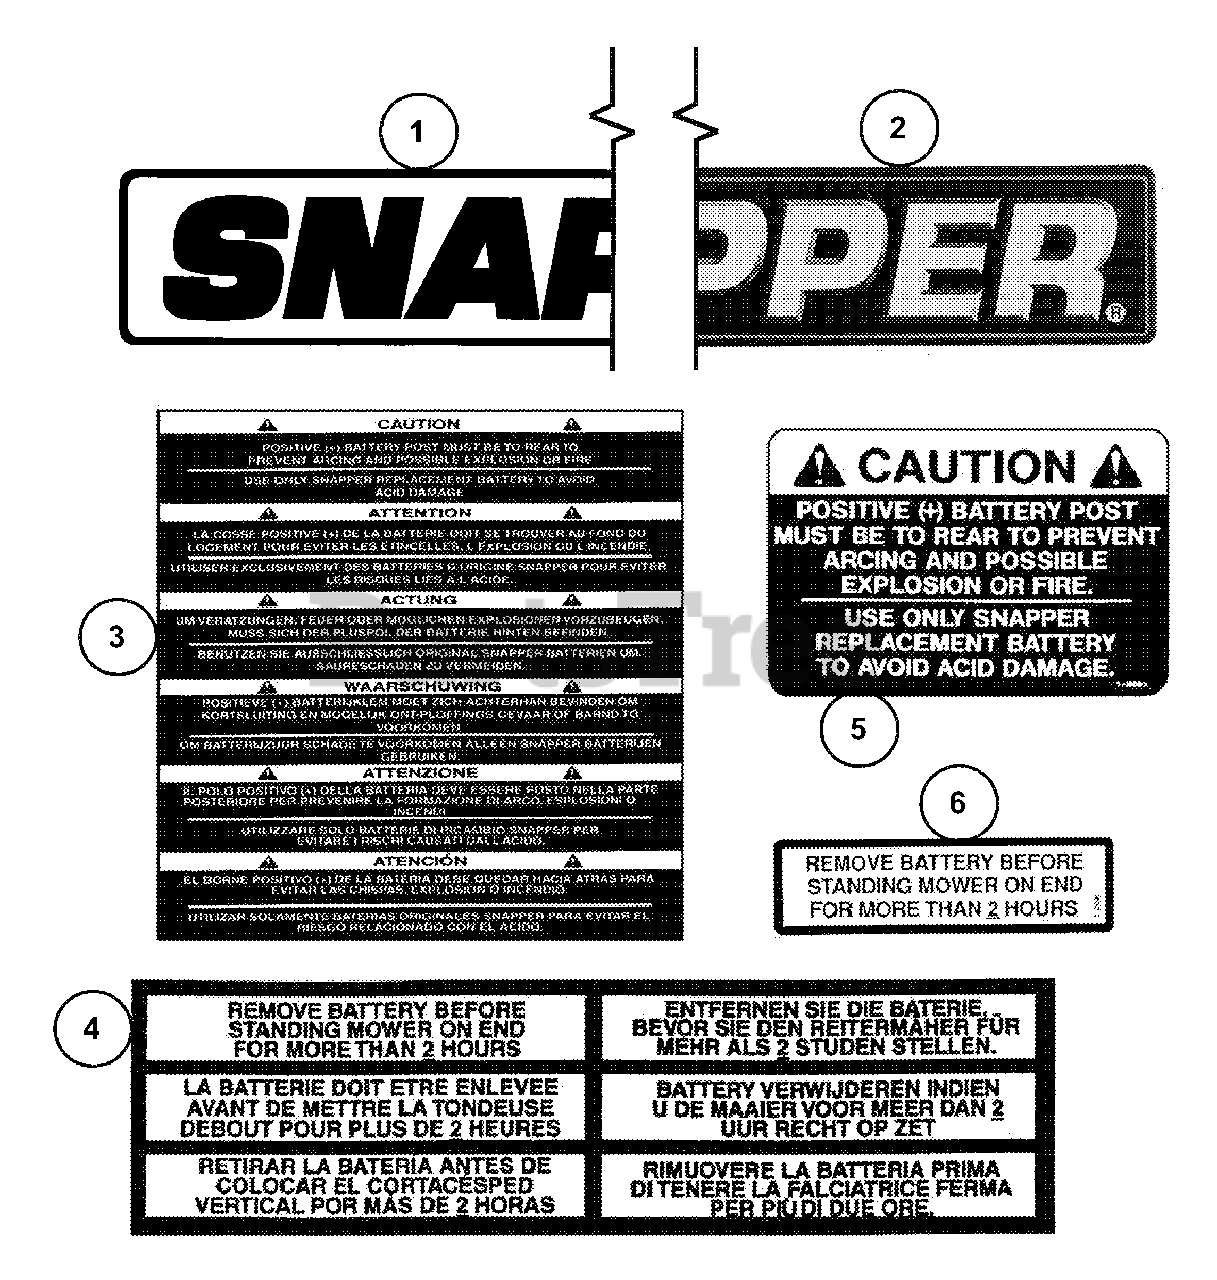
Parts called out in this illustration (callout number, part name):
1	DECAL, Snapper (14-1/2" long, black & white)
2	DECAL, Snapper (14-1/2" long, silver, black & red)
3	DECAL, Caution (Battery) Installation
4	DECAL, Battery Storage (4 Language)
5	DECAL, Battery Caution
6	DECAL, Battery Storage
